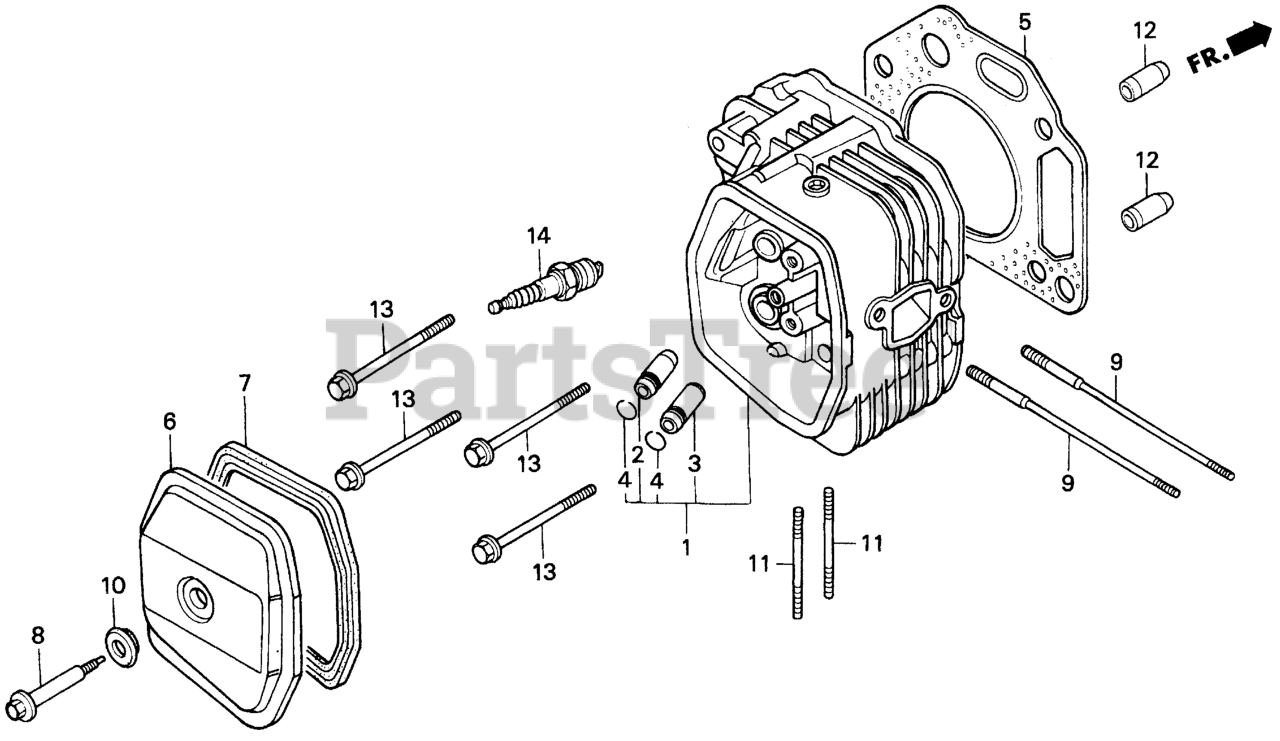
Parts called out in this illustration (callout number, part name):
1	CYLINDER HEAD
2	GUIDE, VALVE (OS)
4	CLIP, VALVE GUIDE
5	GASKET, CYLINDER HEAD
6	COVER, HEAD
7	GASKET, CYLINDER HEAD COVER
8	BOLT, HEAD COVER
9	BOLT, STUD (8X138.5)
10	WASHER, HEAD COVER
11	BOLT, STUD (8X22)
12	PIN A, DOWEL (12X20)
13	BOLT, FLANGE (10X80)
14	SPARK PLUG (BPR5ES) (NGK)
14	SPARK PLUG (W16EPR-U) (DENSO)
